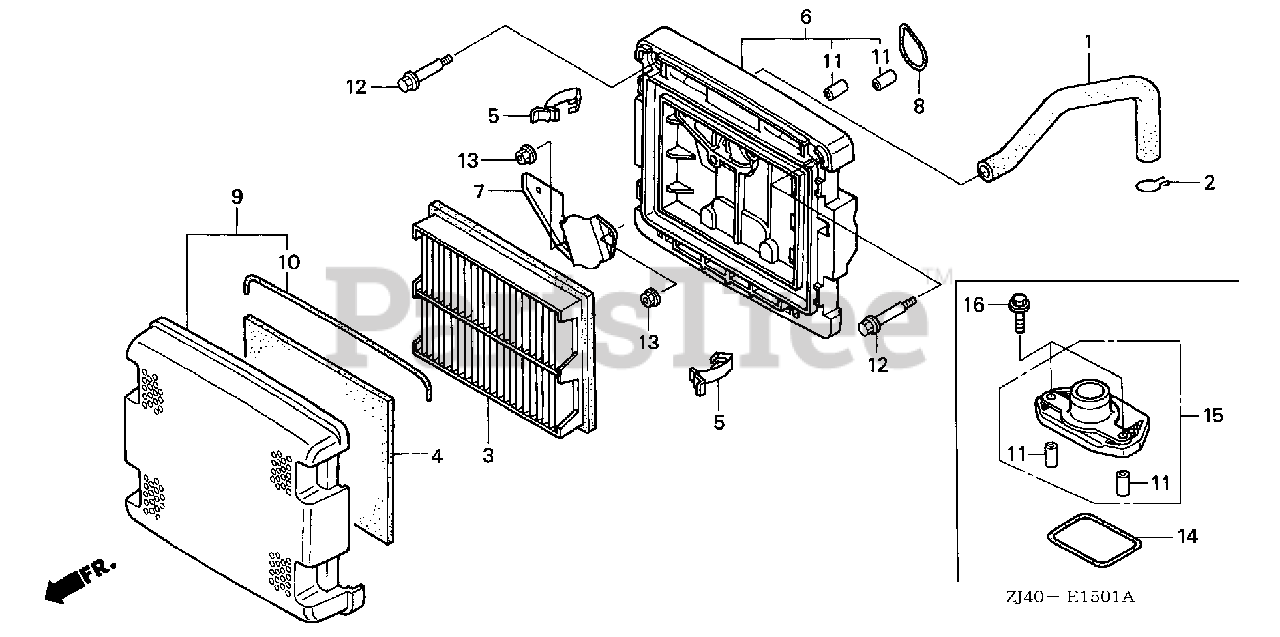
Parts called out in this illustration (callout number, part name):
11	COLLAR A, AIR CLEANER
14	SEAL, AIR CLEANER HOUSING
15	JOINT B, CONNECTING TUBE
16	BOLT, FLANGE (6X28)
